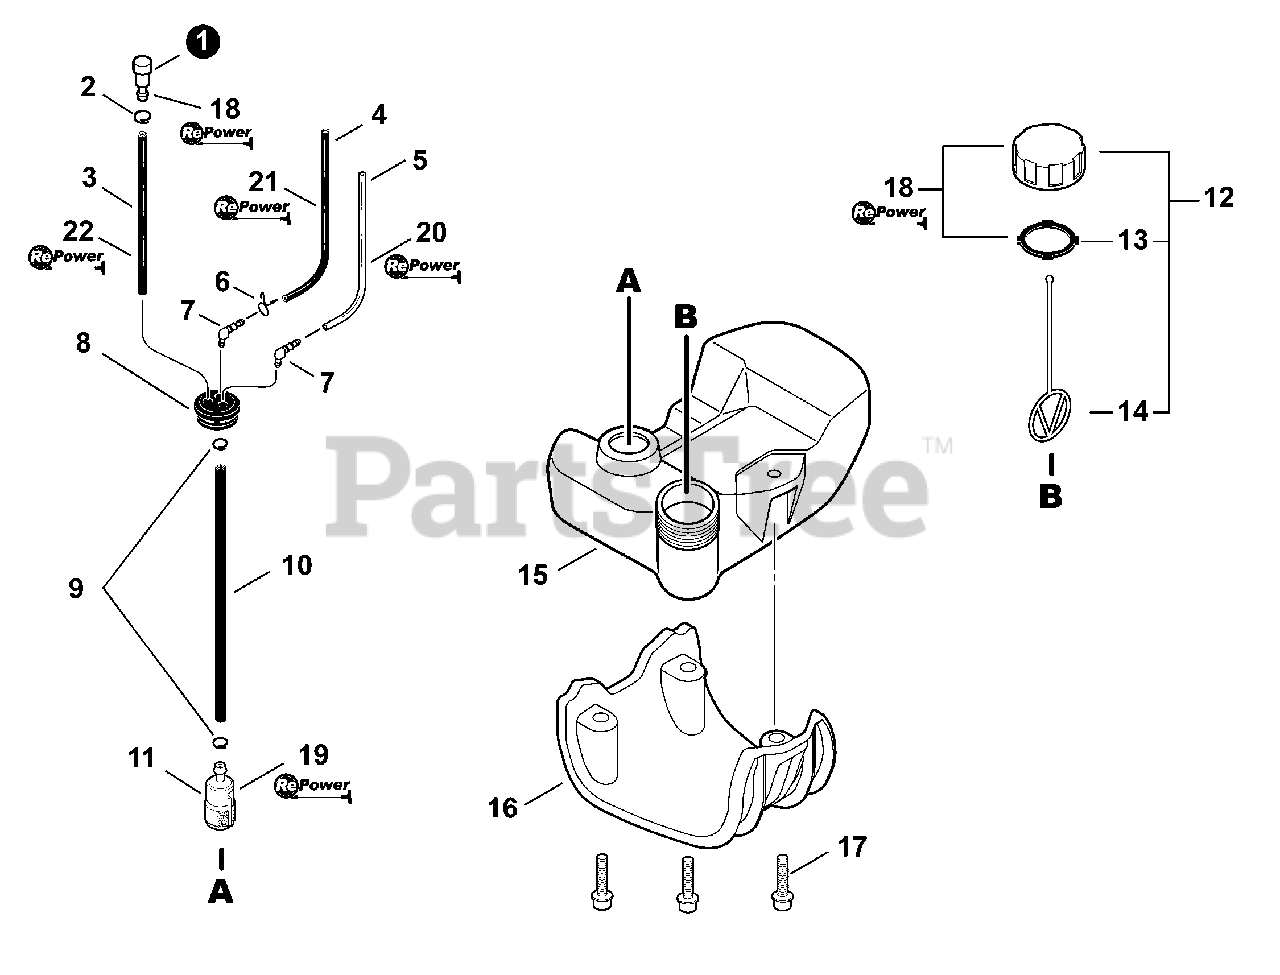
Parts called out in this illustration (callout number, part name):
1	VALVE,CHECK
2	CLIP - 6.5
3	PIPE- 3×6×115 -- BLACK
4	PIPE - 3×5×87 -- BLACK
5	PIPE - 3×6×80 -- CLEAR
6	CLIP - BUTTERFLY
7	CONNECTOR, FUEL PIPE
8	GROMMET, FUEL
9	CLIP - 6
10	PIPE - 3×5×125 -- BLACK
11	FUEL FILTER
12	CAP ASY - ORANGE
13	GASKET,FUEL CAP
14	CONNECTOR,CAP
15	TANK, FUEL
17	SCREW - 5×20
18	RePower CAP AND VENT KIT
19	RePower TUNE-UP KIT
20	PIPE - 25 FT BULK 3×6mm CLEAR
21	PIPE - 25 FT BULK 3×5mm BLACK
22	PIPE - 25 FT BULK 3×6mm BLACK
